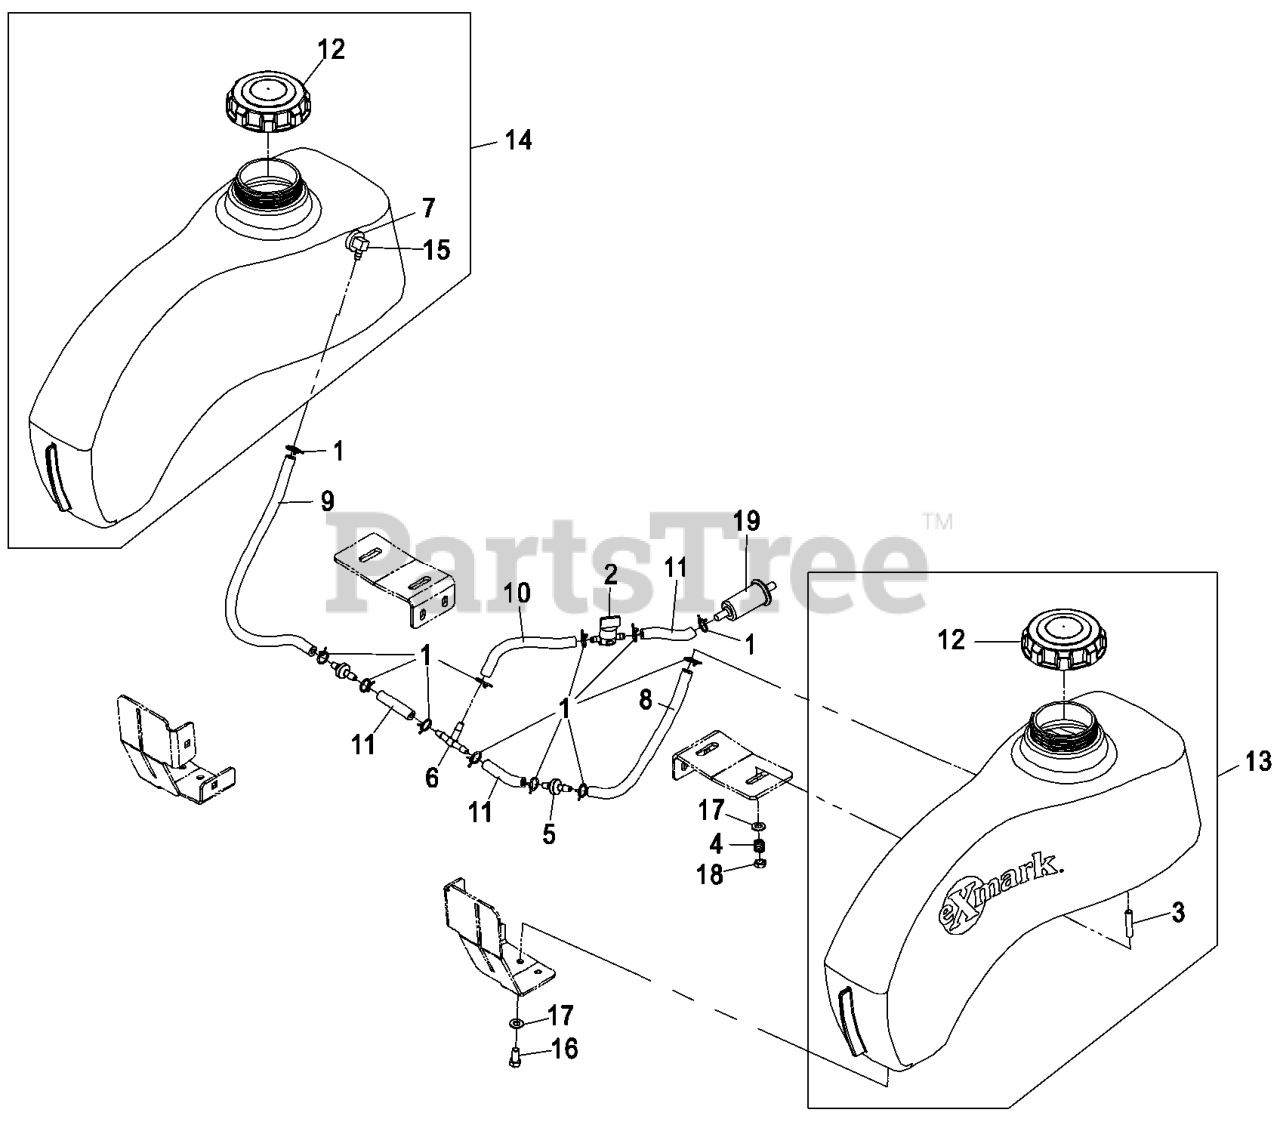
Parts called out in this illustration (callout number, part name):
2	VALVE-FUEL
4	SPRING-TANK, FUEL
5	VALVE-CHECK, FUEL
6	FITTING-TEE, BARBED
7	BUSHING
9	HOSE-FUEL
10	HOSE-FUEL
11	HOSE-FUEL
12	CAP-FUEL, GAS
13	ASM,LH PHAZER TANK W/STUD
14	ASM,PHAZER RH TANK W/STUD
15	FITTING-FUEL (W/LINE AND
16	SCREW-HH
17	WASHER-PLAIN
18	NUT-LOCK, NI
19	Part No 49019-7001 Fuel Filter
